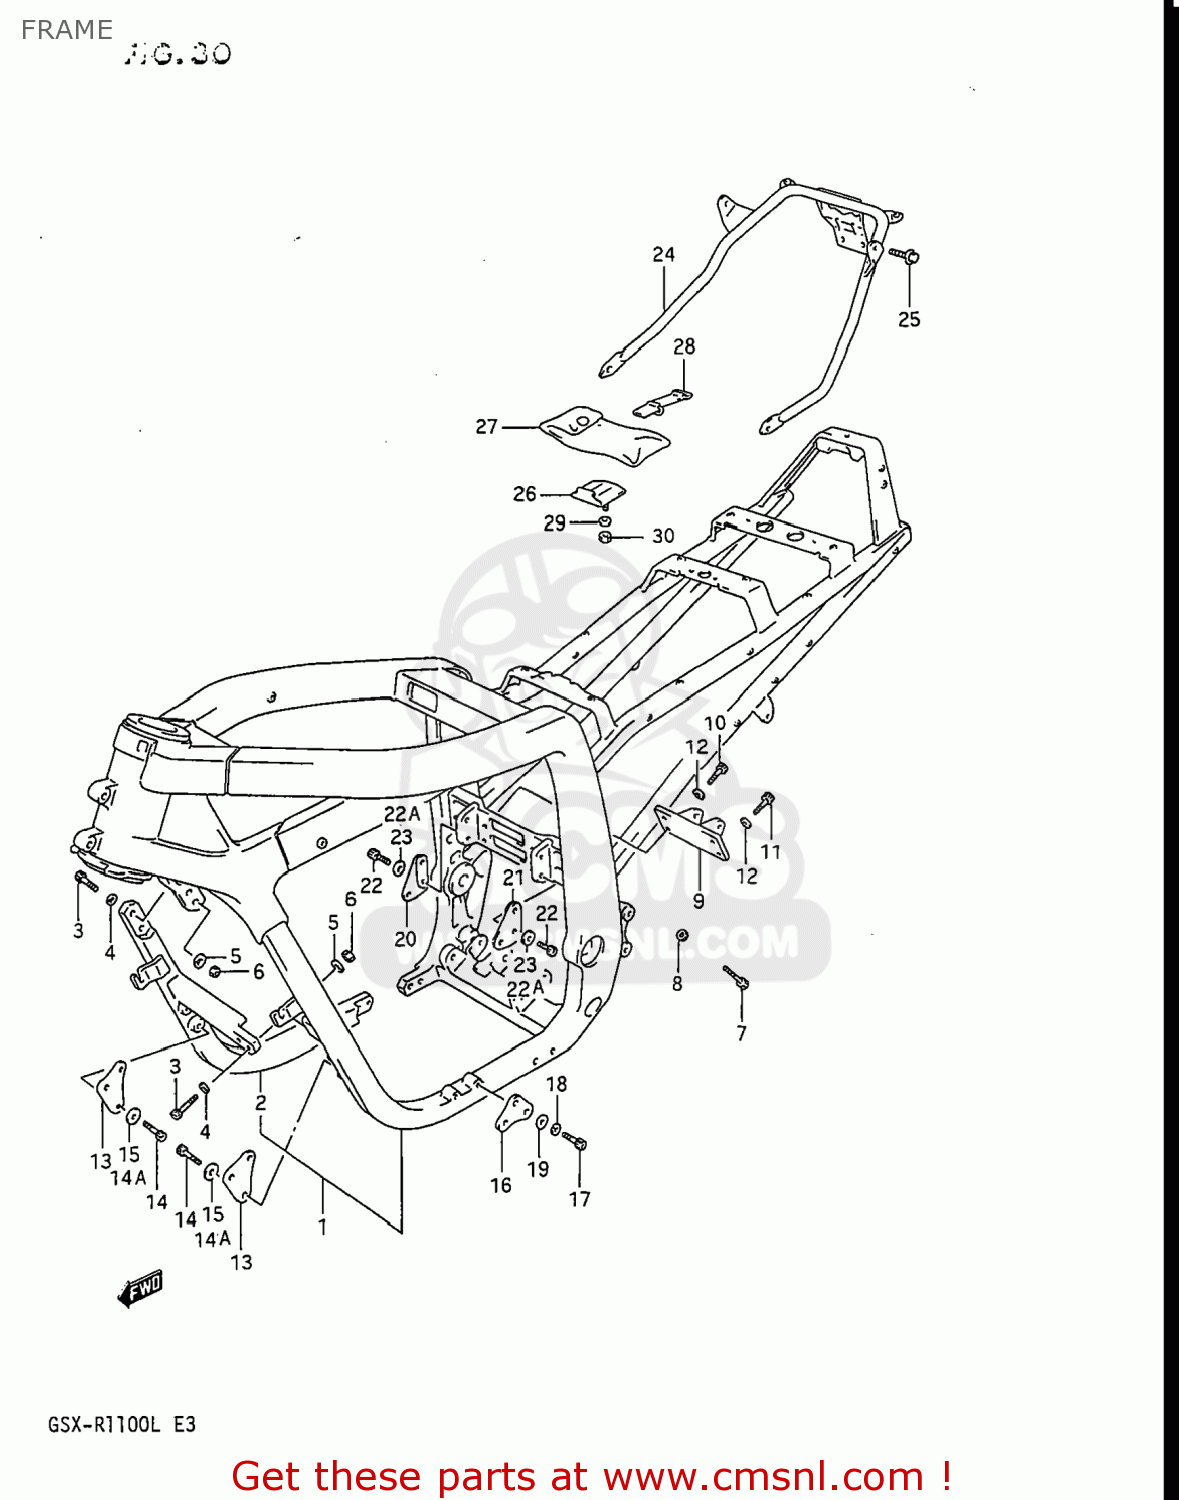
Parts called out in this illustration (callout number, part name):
1	FRAME
2	TUBE COMP,FRAME DOWN,RIGHT
3	BOLT, LH
4	WASHER (10.1X21X2.3)
5	WASHER
6	NUT
7	BOLT
8	GASKET(6.2X11X1) (NAS)
9	BRACKET,REAR CUSHION UNIT
10	BOLT 10X27
11	BOLT, LH
12	WASHER
13	PLATE,ENGINE MOUNTING
14	BOLT, FRONT LH
14A	WASHER,LOCK,8.
15	WASHER (8.2X20X1.6)
16	PLATE,ENGINE MOUNT NO.2
17	BOLT, FRONT LH
18	WASHER,LOCK
19	WASHER (8.2X20X1.6)
20	PLATE,ENGINE MOUNT NO.3,R
21	PLATE,ENGINE MOUNTING NO
22	BOLT(8X22)
22A	WASHER,LOCK,8.
23	WASHER (8.2X20X1.6)
24	GRIP
25	BOLT
26	HOLDER,TOOL
27	TOOL SET
28	BAND
29	WASHER
30	NUT 6MM
